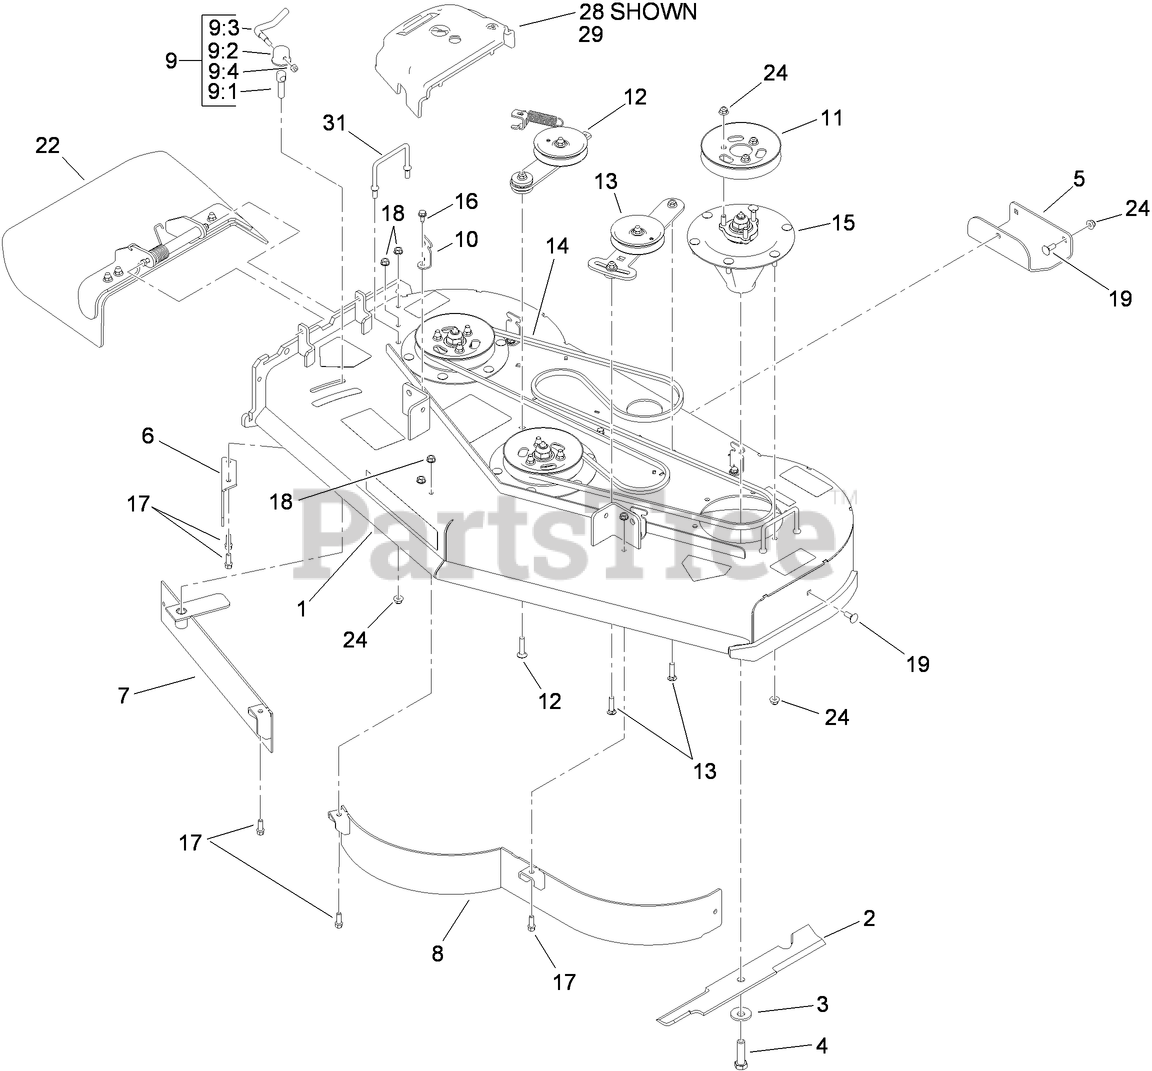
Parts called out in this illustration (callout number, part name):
1	DECK ASM
2	BLADE-18IN, HI FLOW
3	Washer-Blade Bolt, Heavy
4	SCREW-BLADE
6	BAFFLE-DISCHARGE
7	BAFFLE ASM
8	BAFFLE-52 INCH
9	LEVER ASM
9:1	Screw-Lock
9:2	CAP-LOCK
9:3	Lever-Lock
9:4	NUT-LOCK, NI
10	BRACKET-COVER
11	Pulley
12	SPRING IDLER ASM
13	IDLER ADJUST ASM
14	BELT-V
15	SPINDLE ASM
16	SCREW-HWHTF
17	SCREW-HWH
18	NUT-HHF, WHIZ
19	BOLT-CARR
22	DEFLECTOR ASM
24	NUT-HF, NI
28	COVER-BELT, RH
29	COVER-BELT, LH
31	WIREFORM-COVER
